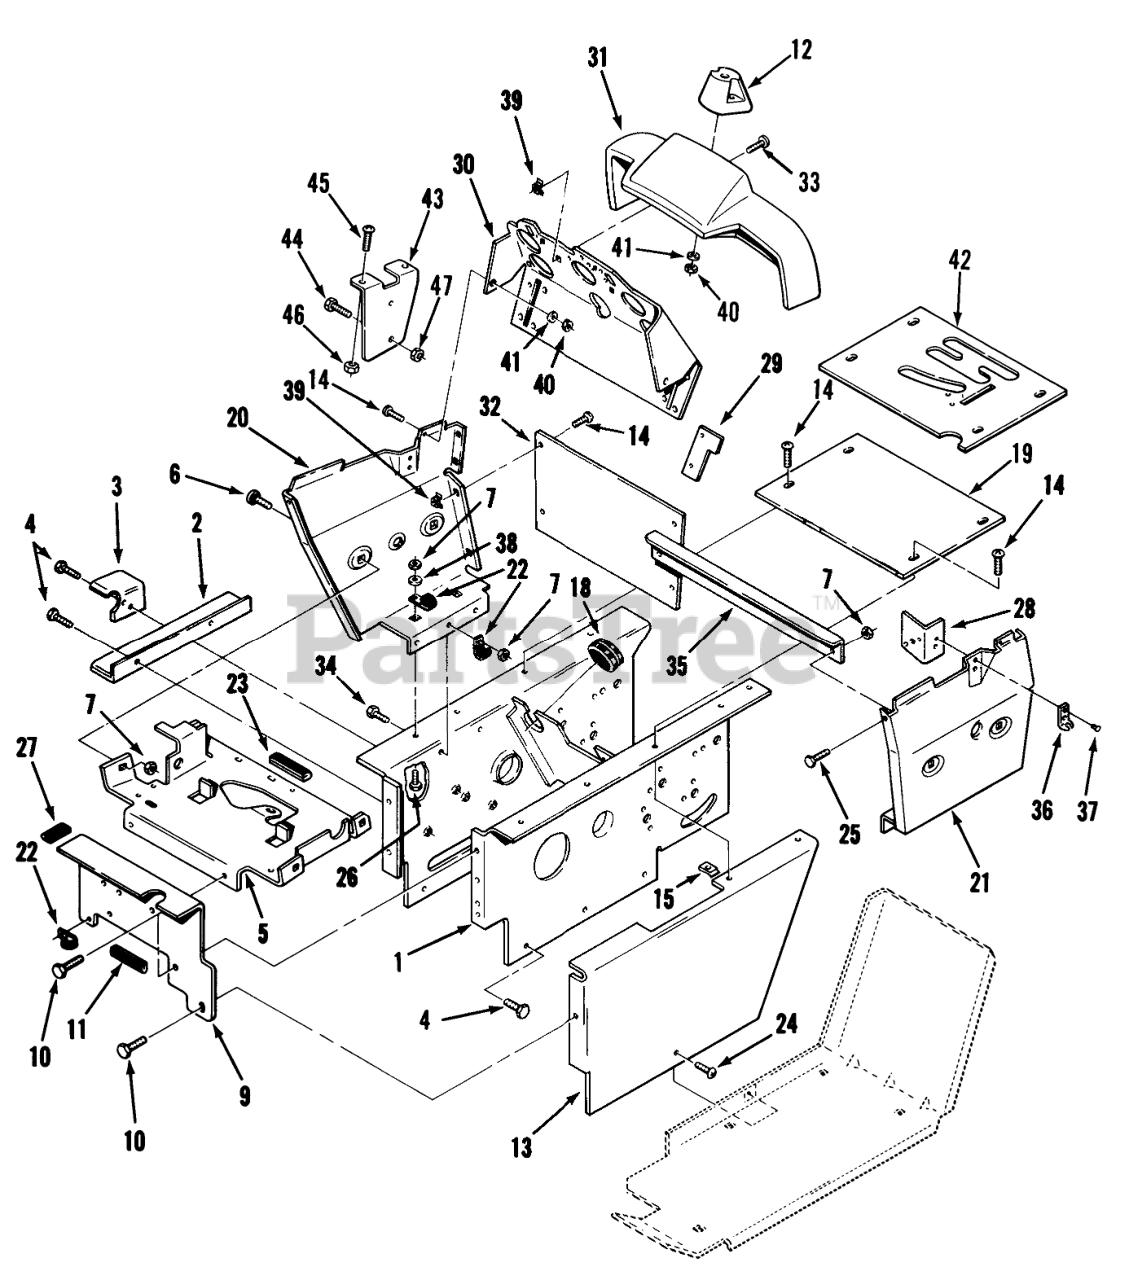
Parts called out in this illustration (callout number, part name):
1	Hoodstand
2	ANGLE-BELT GUARD B
3	Belt Bracket
4	SCREW
5	WLD-SUPPORTB
6	Bolt
7	Nut
9	PLATE-FRT HOODSTA B
10	SCREW
11	EDGE TRIM 2" 102896
12	COVER-STEERING SHAFT
13	COVER-L.H. R
14	SCREW-PPH
18	GROMMET
19	Plate-Hoodstand
20	Panel-RH
21	LS Panel
22	CLIP
23	EDGE TRIM 5" OF 102896
24	Screw
25	H H C S
26	CARRIAGE BOLT -4
27	EDGE TRIM-BULK
28	BRACKET-SWITCH SU
29	STOP-CHOKE
30	ASS'Y-PANEL (3-G) B
31	Console Cover Kit-520-8 (Contains #115621 3-gauge cover, #118400 Steering Cover, (4) 118780 Screw #6 Plastite, & (4) 920270 Washers)
32	PLATE-HOODSTAND B
33	Screw
34	Bolt
35	STIFFENER-PANEL B
36	Latch Keeper (Included in 106825 Hood Latch)
37	RIVET
38	WASHER 5/16 SAE
39	Nut 1/4-20
40	Nut
42	Plate-Shift Cover
43	Bracket-Holder
45	H H C S
46	Nut
47	Nut
